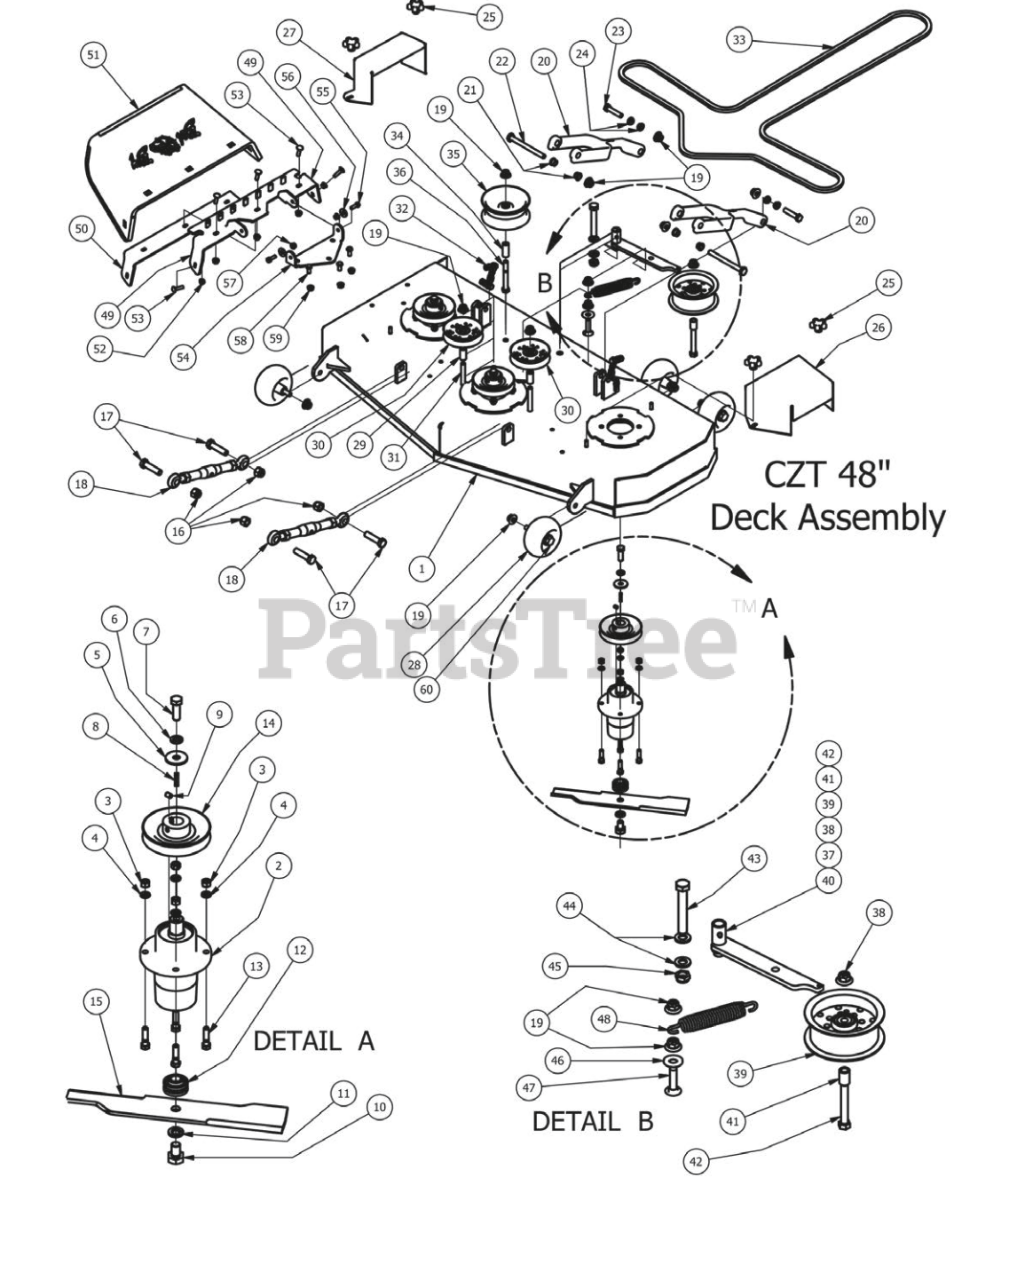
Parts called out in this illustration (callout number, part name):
1	2013 CZT 48" Deck
2	Short Shaft Spindle
3	3/8" Hex Nut
4	3/8" Lock Washer
5	1/2 Belleville Washer
6	1/2" Lock Washer
7	1/2"-20 x 1 1/2 - Grade 5 Fine Thread Bolt
8	1/4" x 1" Key
9	5/16 Set Screw
10	5/8" x 1 1/2" Grade 8 Bolt
11	5/8" Lock Washer
12	Spindle Bearing
13	3/8" x 1 1/2" Hex Bolt
14	5" Deck Pulley
15	48" ZT Blade With Fussion
16	5/8 Std NC Nylock Nut
17	5/8" x 2 1/2" Hex Bolt
18	Turnbuckle (Top Link)
19	1/2-13 Nylon Flange Nut-Orange
20	Deck Arm Assembly
21	Flange Bushing For Deck Arm upper
22	1/2" x 5 1/2" Bolt
23	1/2-13X 2-1/4 GR Hex Bolts
24	Flange for Lower Deck Arm
25	5/16" Knob
26	Pulley Cover
27	1/2 Metal Spindle Cover 48/50"
28	Deck Wheel
29	.502 ID X.75 OD X 1.500 Leng
30	4-3/4 Idler Pulley
31	1/2 x 3 1/2 Flange Bolt Grade 8
32	Chain assembly
33	50" Deck Belt
34	1 3/4" Pulley Spacer
35	5 3/4" Deck Idler Pulley
36	1/2" x 4" Bolt (Grade 8)
37	Deck Idler Assy 48" Components (38,39,40,41,42)
38	1/2-13 Nylon Flange Nut-Orange
39	5 3/4 flat idler-32fI-92-008
40	Deck Idler Bracket
41	.502 x .750 x 1.25 Length Spacer
42	1/2-13 x 3 1/2 GR 5 Hex Bolt
43	5/8" x 4" Hex Bolt
44	.635 ID Plastic Washer
45	5/8" Nylock (1/2 Jam)
46	1/2" Flat Washer
47	1/2 x 2" Carriage Bolt
48	2009 Deck/Pump Idler Spring
49	Upper Hanger
50	Discharge Lower Chute Bracket
51	Rubber Discharge Chute
52	5/16" Nylon Flange Nut
53	5/16" x 1 1/4" Carriage Bolt
54	Discharge Chute Hanger (deck mounted)
55	5/16" x 1" Bolt
56	.360 ID Plastic Washer
57	| 5/16" Nylon Flange Nut
58	3/8" x 3/4" Hex Bolt
59	3/8" Flange Nut
60	Deck Wheel Bolt
